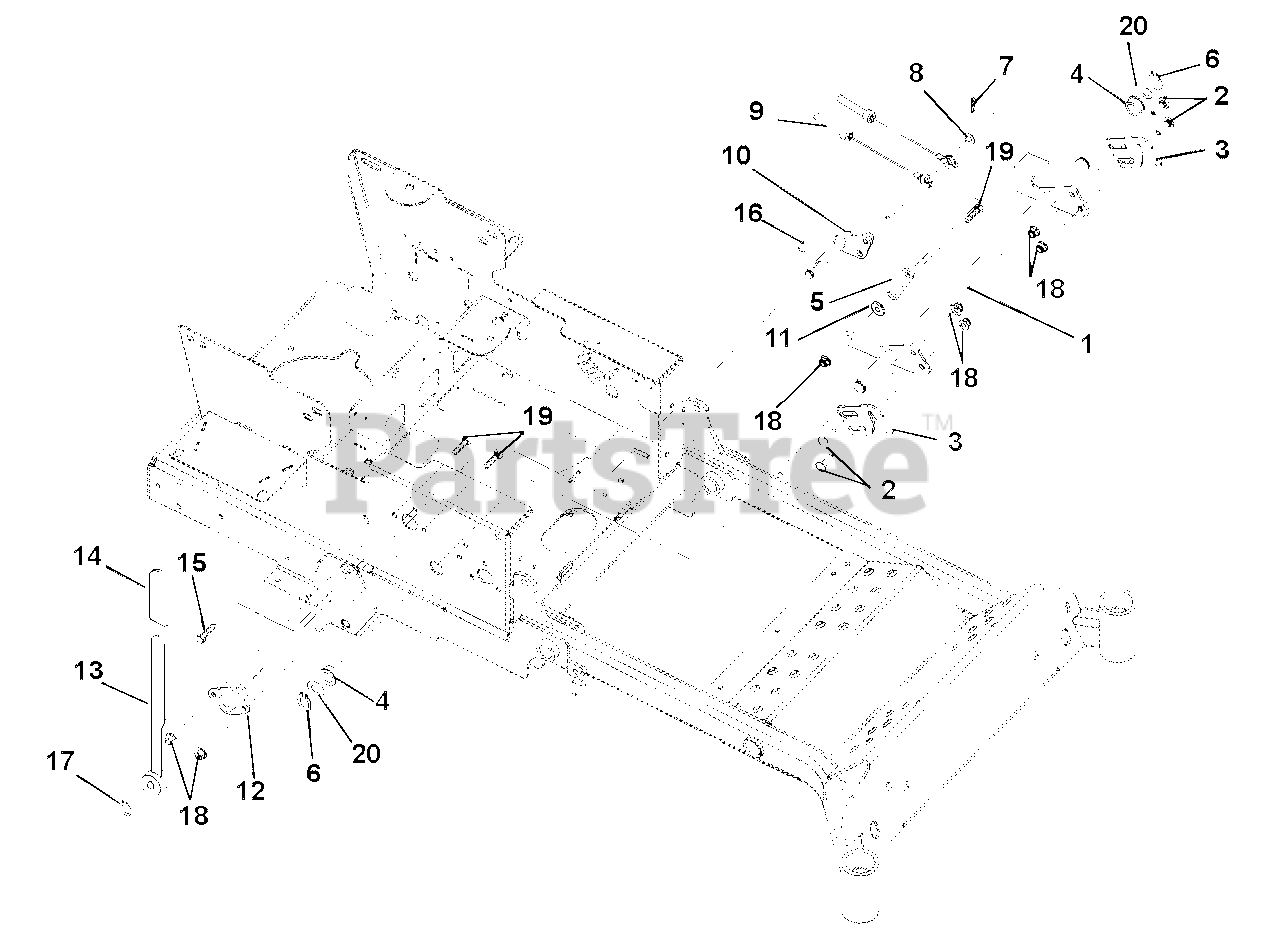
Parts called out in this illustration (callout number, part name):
1	Weldment, Neutral Lock Arm
2	Bolt, Round Head Square Neck .31-18 x 1.00 Grade 5
3	Neutral Lock Latch
4	Bushing, Flange .750 x 1.000 x .625 x 1.250
5	Plate, Neutral Interlock
6	Ring, Retaining, External .689 x .077
7	Pin, Hair, Internal .06 x .18 x .77
8	Washer, Flat, Steel .344 x .688 x .065
9	Cable, Brake Actuating
10	Weldment, Park Brake Arm
11	Bushing, Flange .325 x .499 x .26 x .88
12	Bushing, Flanged
13	Weldment, Parking Brake Lever
14	Grip, Parking Brake
15	Screw, Tapping .38-16 x 1.00 Hex Washer Head
16	Key, Woodruff .13 x .63
17	Ring, Retaining External .50 x .05
18	Nut, Nyloc Flange 5/16-18
19	Bolt, Hex .31-18 x 1.00 Grade 5
20	Washer, Flat-Steel .812 x 1.370 x .100
